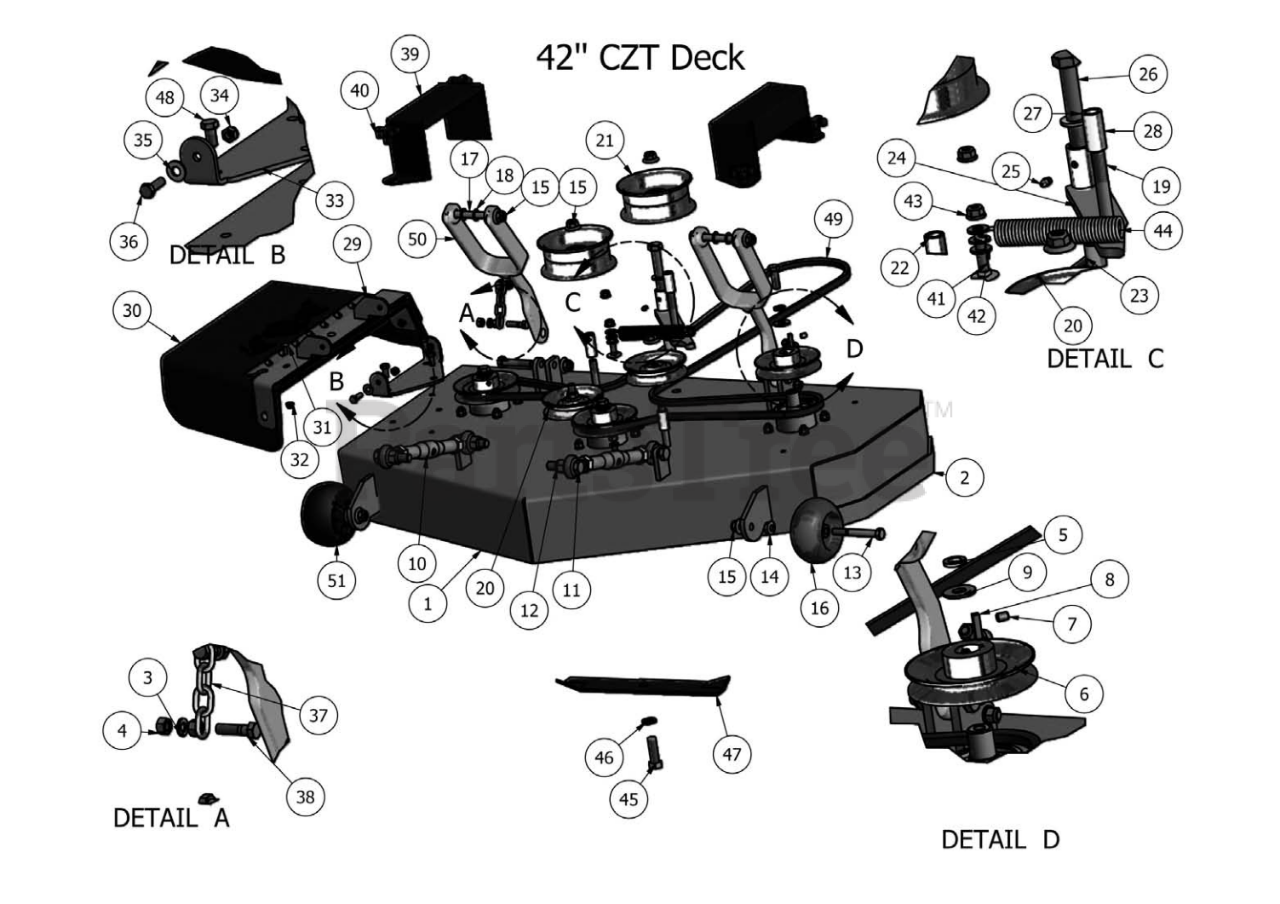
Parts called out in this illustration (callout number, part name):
1	42" Deck (Shell Only)
2	42" Complete CZT Deck
3	3/8" Lock Washer
4	3/8" Hex Nut
5	1/2" Lock Washer
6	5" Deck Pulley
7	3/8" Set Screw
8	1/4" x 1" Key
9	Cup Washer
10	Turnbuckle
11	5/8" x 2 1/2" Hex Bolt
12	5/8" Nylock (1/2 Jam)
13	1/2" x 4" Bolt (Grade 8)
14	1/2" Flange Nut
15	1/2-13 Nylon Flange Nut-Orange
16	Anti-Scalp Rollers (Roller Only)
17	1/2" x 4 1/2" Bolt
18	1/2" Brass Washer
19	1/2 x 3 1/2 Flange Bolt Grade 8
20	4 3/4" Idler Pulley
21	5 3/4" Deck Idler Pulley
22	1 3/4" Pulley Spacer
23	5/8" ID x 1 1/8" Brass Bushing
24	Deck Idler Arm
25	1/4" Drive in Grease Fitting
26	5/8" x 4" Hex Bolt
27	.635 ID Plastic Washer
28	1.25" Pulley Spacer
29	Rubber Discharge Chute Assembly
30	Rubber Discharge Chute (Rubber Only)
31	1 1/4" x 5/16" Carriage Bolt
32	1/4-20 Hex Flange Nuts Zinc w/Serrations
33	Discharge Chute Hanger (deck mounted)
34	5/16Flange Nut
35	.360 ID Plastic Washer
36	5/16" x 1" Hex Bolt
37	ZT Deck Hanger Chain Assembly
38	3/8" x 1 1/2" Hex Bolt
39	42" Spindle Cover
40	5/16" Knob
41	3/8 x 1-1/2 Carriage Bolt
42	3/8" Flat Washer
43	3/8" Nylock Flange Nut
44	Deck Idler Spring
45	5/8" x 1 1/2" Fine Threaded Bolt
46	5/8" Lock Washer
47	42 inch High Lift Fusion Blade
48	3/8" x 3/4" Hex Bolt
49	42" CZT Deck Belt
50	Deck Arm Assembly
51	Anti-Scalp Roller Assembly
